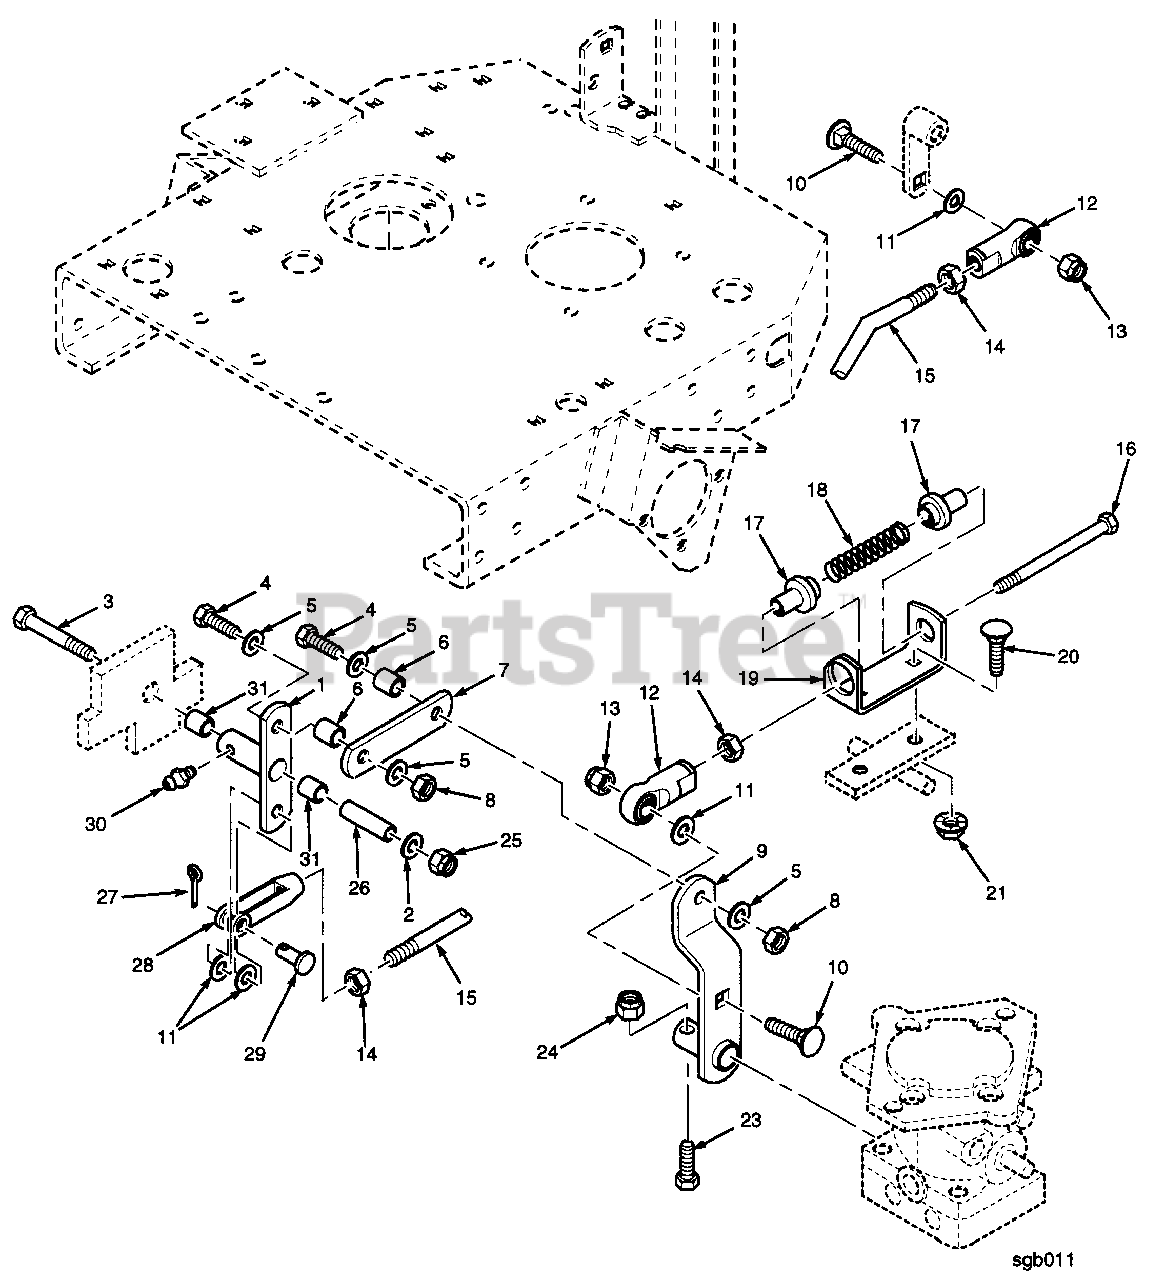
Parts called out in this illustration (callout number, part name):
1	CONTROL LINKAGE, BELLCRANK(INCLUDES 30, 31)
2	FLATWASHER, 5/16(.375 X .875 X .083)
3	BOLT, HEX HEAD 5/16-18 X 2-3/4
4	BOLT, HEX HEAD 3/8-16 X 1
5	FLATWASHER, 3/8(.406 X .812 X .065)
6	SLEEVE, PUMP CONTROL LINK
7	LINK, SPEED CONTROL
8	HEX LOCKNUT, 3/8-16
9	CONTROL ARM, PUMP
10	CARRIAGE BOLT, RH SH SQNK 3/8-16 X 1-1/2
11	FLATWASHER, 3/8(.391 X .938 X .105)
12	ROD END, RH FEMALE THD 3/8-24
13	HEX LOCKNUT, ELASTIC STOP 3/8-16
14	HEX NUT, 3/8-24
15	CONTROL ROD
16	BOLT HEX HEAD, 3/8-24 X 6-3/4
17	BUSHING, SPRING KEEPER
18	SPRING, NEUTRAL RETURN
19	RETAINER, NEUTRAL SPRING
20	CARRIAGE BOLT, 5/16-18 X 1
21	SERR. FL. HEX NUT 5/16-18
23	BOLT, HEX HEAD 1/4-20 X 1-1/4
24	HEX LOCKNUT, ELASTIC STOP 1/4-20
25	HEX LOCKNUT, ELASTIC STOP 5/16-18
26	SLEEVE, CONTROL ARM
27	COTTER PIN, 3/32 X .75
28	CLEVIS, PUMP CONTROL
29	PIN, CLEVIS 3/8
30	GREASE FITTING, 1/4-28 SELF TAP
31	BUSHING, BRONZE
